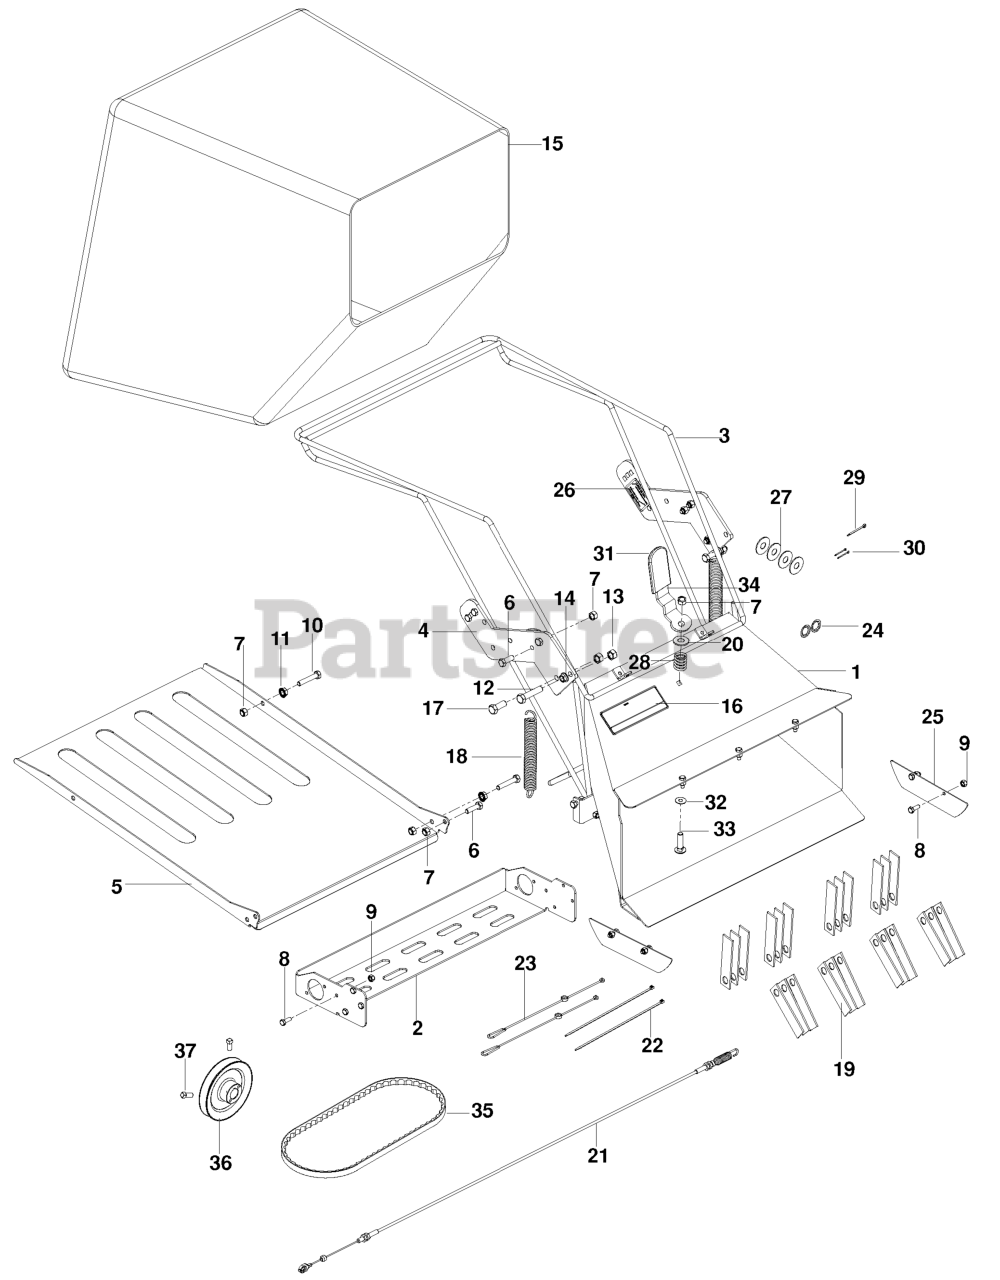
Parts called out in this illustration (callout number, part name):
1	CHUTE W/DECAL ORANGE
2	BAGGER TRAY
3	BAG FRAME, BLACK
4	EXTENDER GREY
5	SAFETY DOOR ORANGE
6	HCS 5/16C X 1
7	NUT 5/16 NYLOC
8	HCS 1/4C X 3/4 HCS
9	NUT.1/4-20.HEX.NYLOC.ZD
10	HCS 5/16C X 1 3/4
11	NUT 5/16C WHIZ
12	HCS 3/8C X 2
13	NUT 3/8-16 NYLOC
14	NUT 3/8C WHIZ
15	CATCHER BAG
16	DECAL, BAGGING GRAPHIC
17	HCS 3/8-16X1.GRD.5.ZD
18	SPRING BAGGER
20	WASHER 5/16 FLAT
21	CABLE 46.5" POWER RAKE
22	TIE, PLASTIC
24	NUT 5/8 PUSH
25	SIDESHIELD
26	DECAL, HANDLE PIN
27	WASHER 5/8 FLAT
28	COMPRESSION SPRING
29	COTTER PIN
30	COTTER PIN 3/32 X 3/4
32	WASHER 3/8 FLAT
33	RHSNB 5/16-18X1 3/4
35	BELT-COGGED
36	PULLEY, 4.5"
37	SCREW 5/16C X 5/8 SQ HEAD
